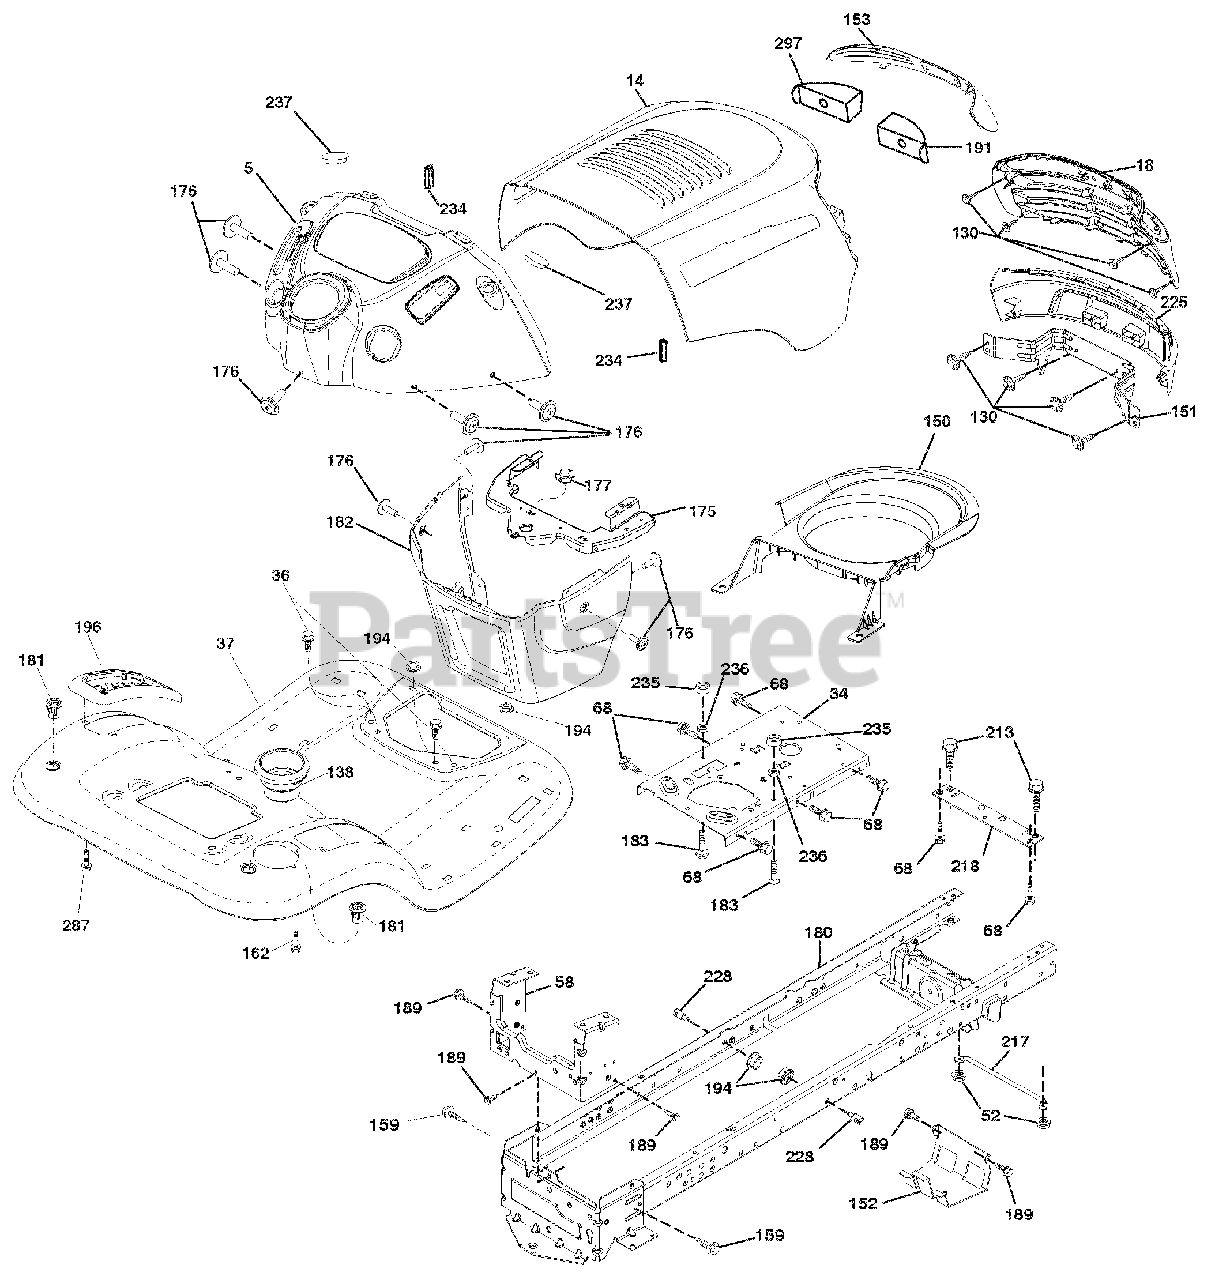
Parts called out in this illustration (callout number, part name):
18	GRILLE
34	PLATE.ENGINE.WELDED.CHASSIS
36	SCREW.5/16-18X3/4.SMGML.TAP/R
37	FENDER.TLT W/CPH
52	Nut, Hex, Crownlock 5/16-18
58	DRAWBAR.UPPER.2PC.SML.FENDER
68	SCREW.THDROL.5/16-18 X 1/2TYTT
138	CUPHOLDER TL TEX 428
150	AIR DUCT.INTAKE.B&S
151	Bracket Pivot
152	SHIELD.BROWNING.W/TEX
153	LENS, ARIENS
159	SCREW.HEXWSH THDR3/8-16X3/4.BL
162	SCREW.HEX.WSH.HI-LO.1/4X1/2UNC
175	CROSSMEMBER.LT
176	SCREW.#10-24X5/8.RND.QUDRX.GIM
177	BUSHING.STEERING.LT
180	CHASS.WLDMT.TL.12GA/2PC.18/22"
181	BUSHING MNT FEND CRGO BLK TEX
182	DASH LOWER
183	BOLT.FIN.HEX.5/16-18 UNC X1-1/
189	SCREW.5/16-18X3/4.SMGML.TAP/BL
191	INSERT REFLECTIVE RH
194	Nut, Lock Hex Flange 5/16-18 u
196	CONSOLE ASSEMBLY
213	Bolt, Hex Head 5/16-18 x 3/4
217	ROD.PIVOT.HOOD
218	X-PIECE.HOOD.STOP.NON/STEALTH
225	BUMPER
228	STUD.FASTNER.W/'D'ANTI-ROTATIO
234	BUMPER HOOD
235	SPACER.FENDER
236	NUT.CENTER LOCK.5/16-18 UNC
237	PLUG.MOUNT.CARGO
287	SCREW.HEX.WASHEAD.1/4-20 X 3/8
297	INSERT REFLECTIVE LH
